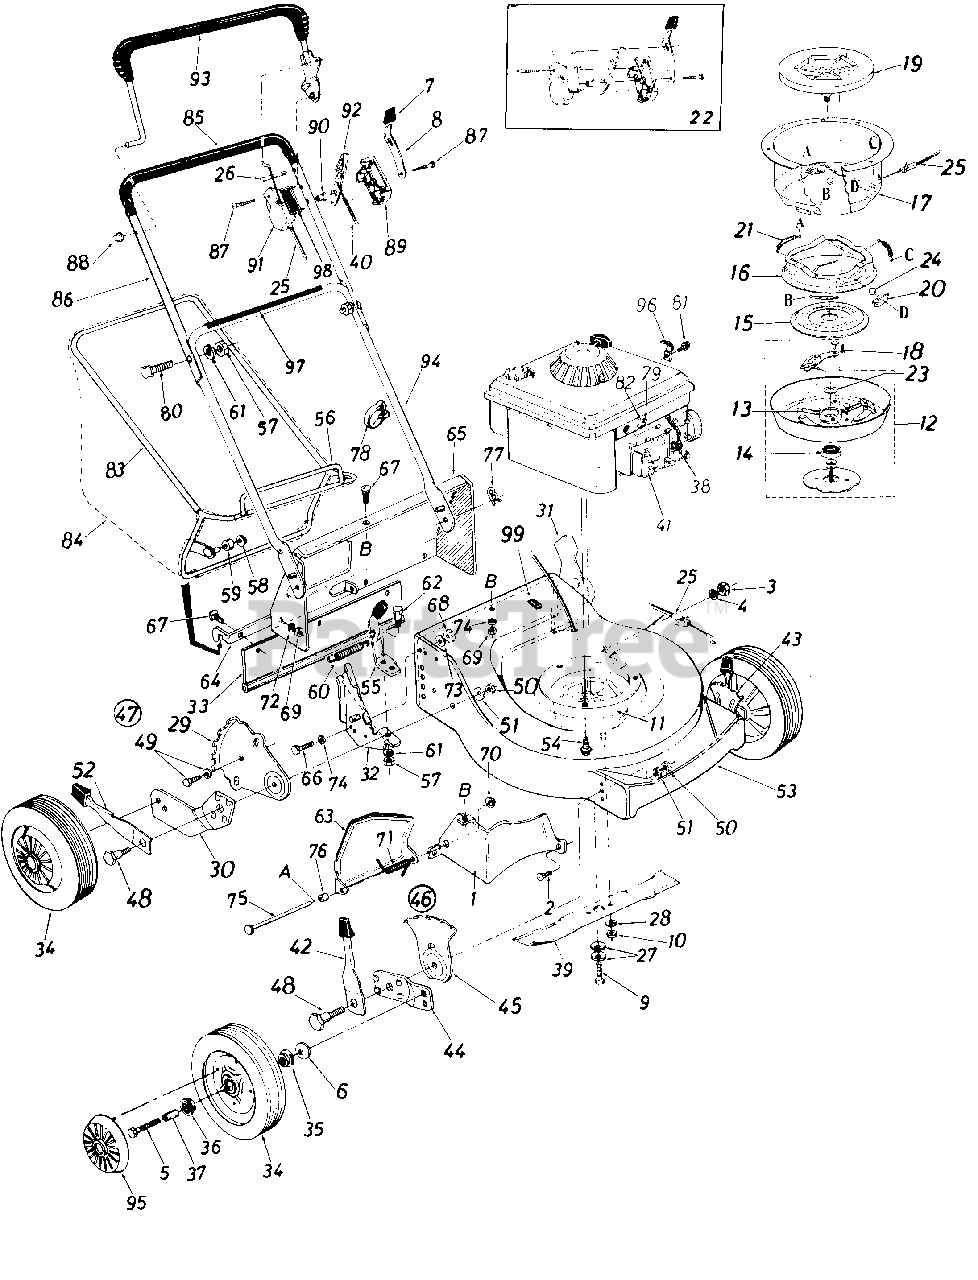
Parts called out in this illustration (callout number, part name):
1	Rear Baffle
2	Carriage Bolt 1/4-20 x .50" Lg.
3	Hex Nut 1/4-20 Thd.*
4	L-Wash. 1/4" I.D.
5	Axle Bolt
6	Bell-Wash. .400" I.D. x .88"
7	Spring Lever Knob
8	Lockout Spring
9	Hex Scr. 3/8-24 x 2.00" Lg. (Grade 8)
10	Hex Nut 3/8-24 Thd. (Grade 8)
11	Blade BrakelClutch Ass'y.-Comp.
12	Clutch Blade Housing Ass'y.
13	Compression Spring
14	Ball Brg. .669" I.D. x 1.574" O.D.
15	Clutching Cone
16	Brake Cup Cone
17	Clutch Housing
18	Hex Tap L-Scr. 1/4-20 x .75"
19	Fan Adapter
20	Ball Block
21	Extension Spring
22	Control Housing Comp.
23	Fl-Wash. .690" I.D. x 1.060" O.D.
24	Steel Ball .500" Dia.
25	Clutch Cable-46.0"
26	Lock Pin .314" Dia. x 1.70" Lg.
27	Bell-Wash. .400" I.D. x .88" O.D.
28	L-Wash. 3/8" I.D.*
29	Rear Index Plate
30	Rear Pivot Bar-R.H.
31	Handle Brkt. Ass'y.-L.H.
32	Handle Brkt. Ass'y.-R.H.
33	Rear Flap Ass'y.
35	Bearing
36	Beari ng
37	Spacer
38	Spark Plug Insulator
39	21" Blade
40	Throttle Wire-58" (Black)
41	Engine
42	Spring Lever wlKnob
43	Front Height Adj. Ass'y.-L.H.
44	Front Pivot Bar
45	Front Index Plate
46	Front Height Adj. Ass'y.-L.H.
47	Rear Height Adj. Ass'y.-R.H.
48	Shld. Bolt .500" Dia. x .375
49	Hex Wash. Hd. Tap Scr. 1/4 x.62" Lg.
50	Hex Nut 3/8-16 Thd.*
51	Bell-Wash. .391" I.D. x 1.38" O.D.
52	Spring Lever w/Knob
55	Grass Catcher Lock Lever
58	Push Nut 3/8" Rod
59	Plastic Roller
60	Tension Spring
61	L-Wash. 5/16" I.D.
62	Shld. Bolt .437" Dia. x .162" Lg.
63	Chute Door
64	Grass Catcher Hitch Brkt.
65	Rear Discharge Deck Section
66	Hex Bolt 1/4-28 x .75" Lg.
67	Carr. Bolt 1/4-20 x .75" Lg.
68	Hex Nut 1/4-28 Thd.
69	Sems Nut 1/4-20 Thd.
70	Push Nut 1/4" Rod
71	Torsion Spring
72	Fl-Wash. .285" I.D. x 1.25" O.D.
73	Bell-Wash. 1/4" I.D. x .88" O.D.
74	L-Wash. 1/4" I.D.
75	Hinge Pin .250" Dia. x 7.88" Lg.
76	Spacer .262" I.D. x .31" O.D.
77	Intern. Cot. Pin 5/16" Dia.
78	Cable Tie
79	Hex Sems Scr. #10-32 x .62"
80	Curved Carriage Bolt 5/16-18 x 1.38" Lg.
81	Hex B-Tap Scr. #10 x .38" Lg.
82	Casing Clamp
83	Grass Catcher Upper Frame
84	Grass Bag (Without Flip Top)
86	Upper Handle (Chrome)
87	Truss Mach. HI-B Tap Scr. #12 x 1.50" Lg.
88	Cap Speed Nut 5/16" Rod
89	Control Panel Half
90	Control Disc Pin
91	Clutch Panel Half
92	Throttle Control Lever
93	Control Handle-L.H.
94	Lower Handle (Chrome)
95	Hub Cap
96	Casing Clamp
97	Instruction Label-Handle
98	Control Label-Throttle
99	Plastic Plug
